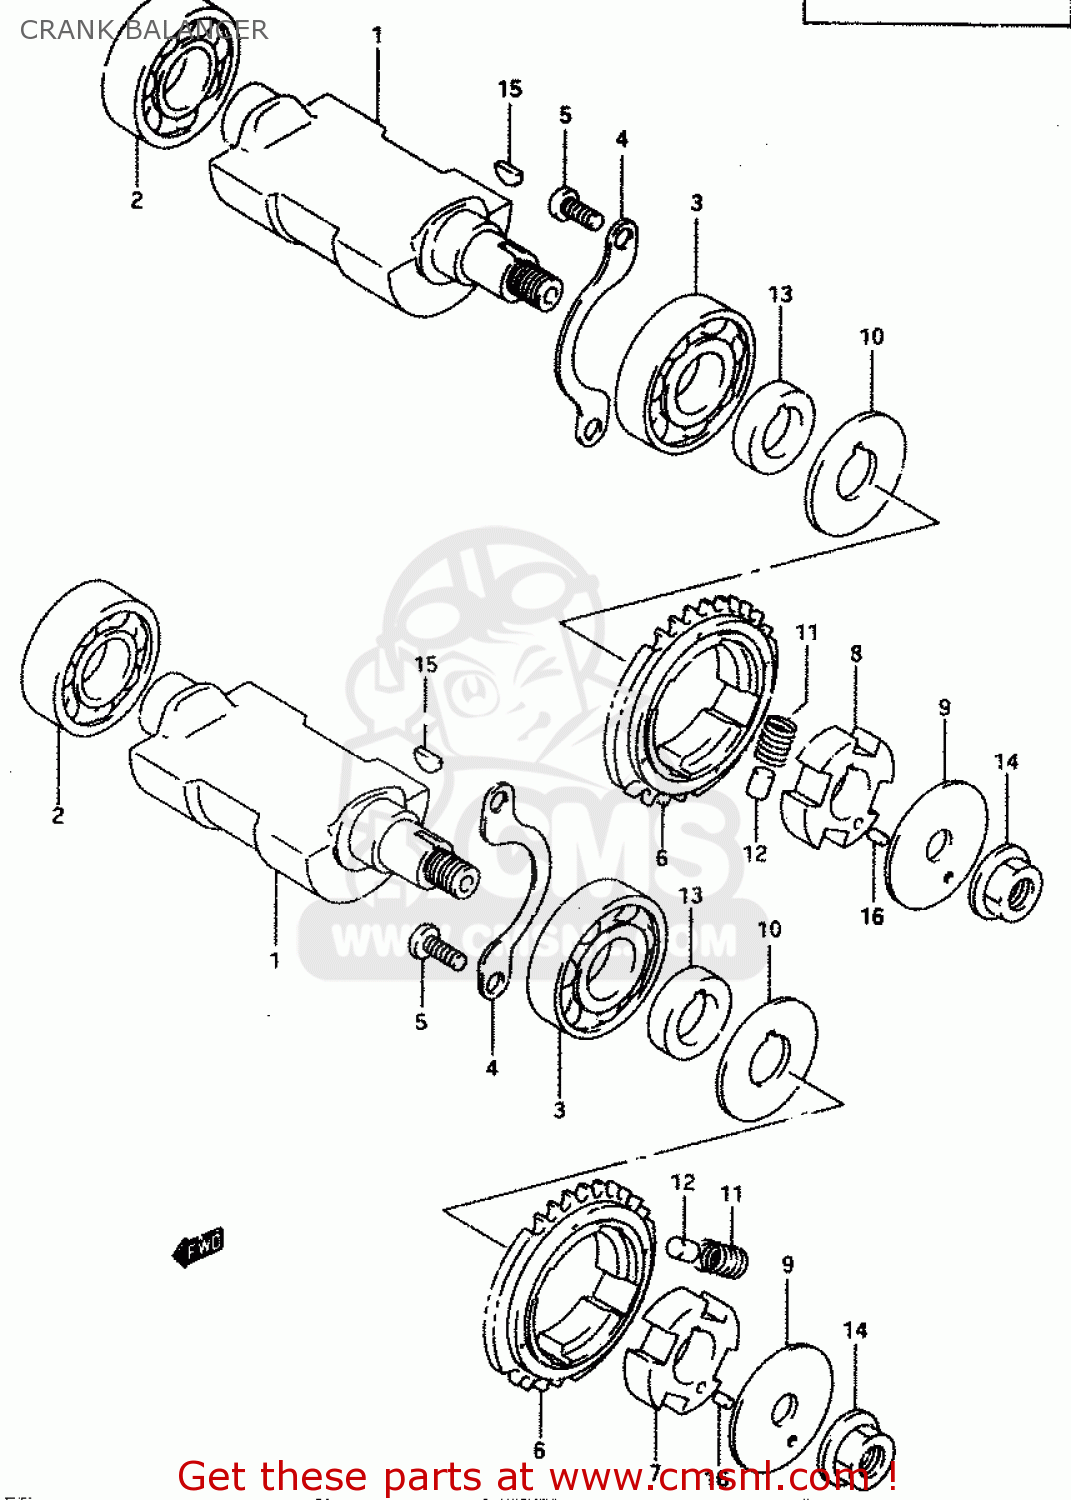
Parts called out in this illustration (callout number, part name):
1	BALANCER,CRANK
2	BEARING(20X42X12)
3	BEARING(20X47X12)
4	RETAINER,CRANK BAL BEARING
5	SCREW
6	SPROCKET,CRANK BAL DRIVEN
7	RACE,BALANCER DRIVER SPOCKET,INNER
8	RACE,BALANCER DRIVER SPOCKET,INNER
9	WASHER (10X39X1.6)
10	WASHER
11	SPRING
12	PIN(6X8.8)
13	SPACER (16X26X7.5)
14	NUT (M10X1.25X9)
15	KEY
16	PIN(3X11.3)
